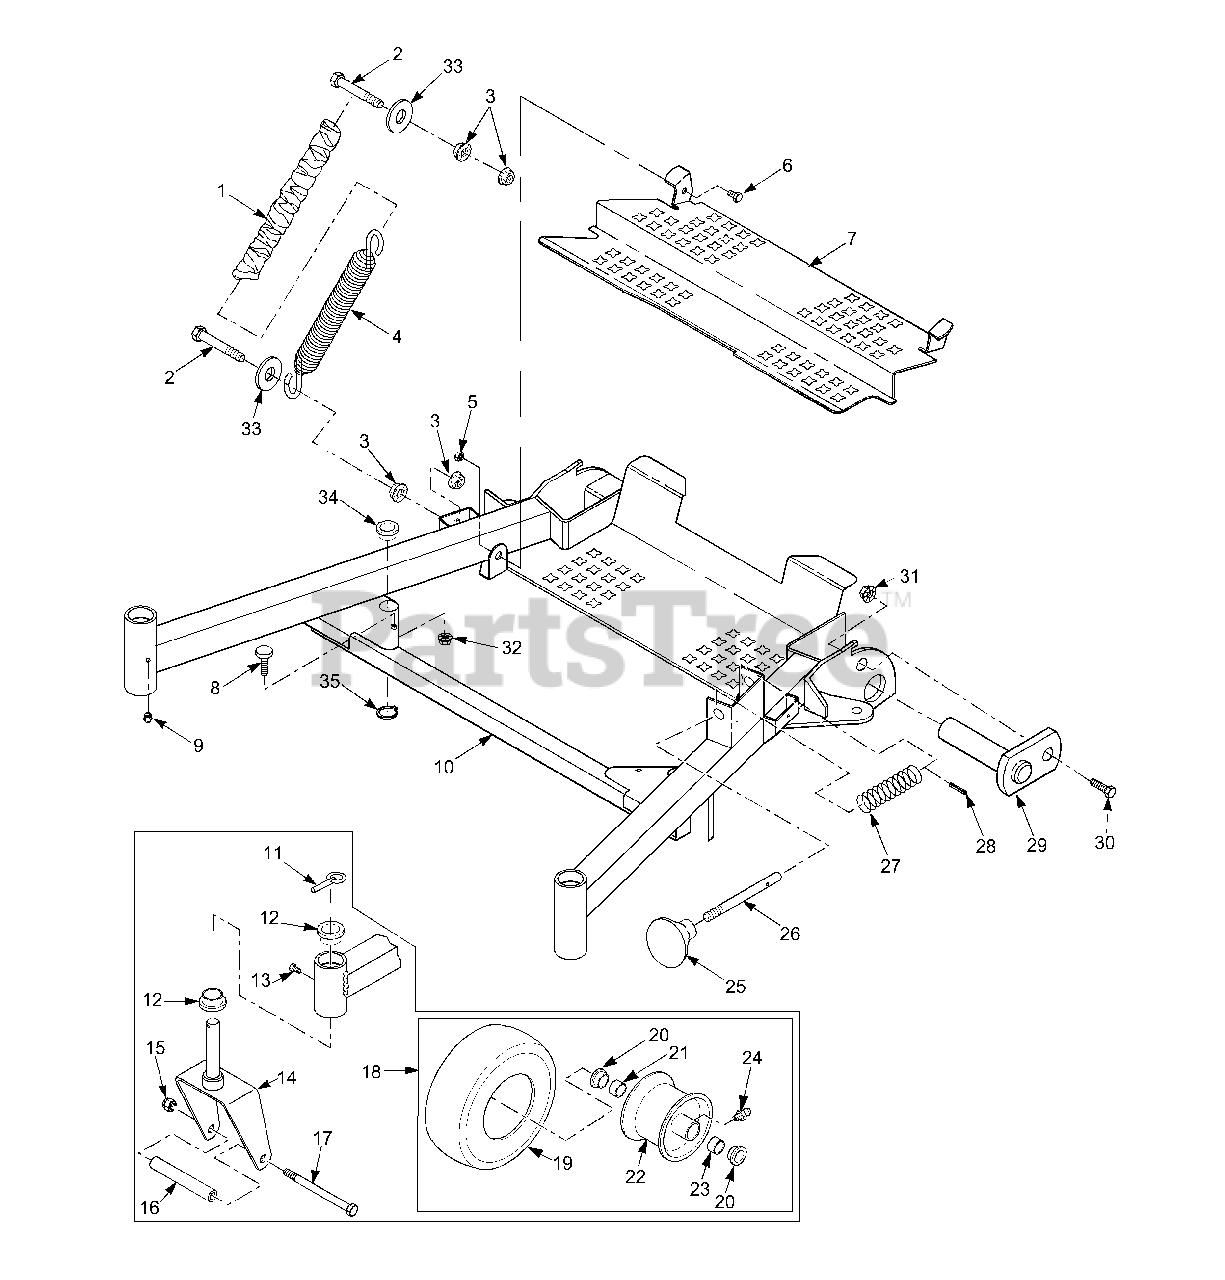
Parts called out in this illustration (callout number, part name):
1	Cover, Spring
2	Bolt, Hex Head 1/2-13 x 2.5"
3	Nut, 1/2-13 Serrated Flange
4	Spring, Cutter Deck LIft
5	Nut, 3/8-16 Elastic Stop
6	Bolt, Hex Head 3/8-16 x 1"
7	Footplate
8	Bumper, Rubber
9	Fitting, Grease
10	Frame, Cutter Deck Mounting
11	Pin, Quick
12	Bushing, 1" ID Oilite
13	Plug, 1/4-28
14	Yoke, Caster
15	Nut, 1/2-13 Elastic Stop
16	Spacer
17	Bolt, Hex Head 1/2-13 x 6.5"
18	Wheel, Caster 11 x 4.0-5
19	Tire, 11 x 4.0-5
20	Retainer
21	Roller Bearing .625 x 3.25"
22	Rim, 5.0 x 3.25"
23	Roller Bearing .625 x 1.0"
24	Fitting, Grease
25	Knob, Cutter Deck Release
26	Rod, Threaded
27	Spring
28	Pin, Roll 3/16 x 1.5"
29	Pin, Deck Frame Pivot
30	Bolt, Carriage 5/16-18 x 1"
31	Nut, 5/16-18 Elastic Stop
32	Nut, 5/16-18 Serrated Flange
33	Flatwasher, 5/8-.688 x 1.750 x .134
34	Bushing
35	Snap-Ring
